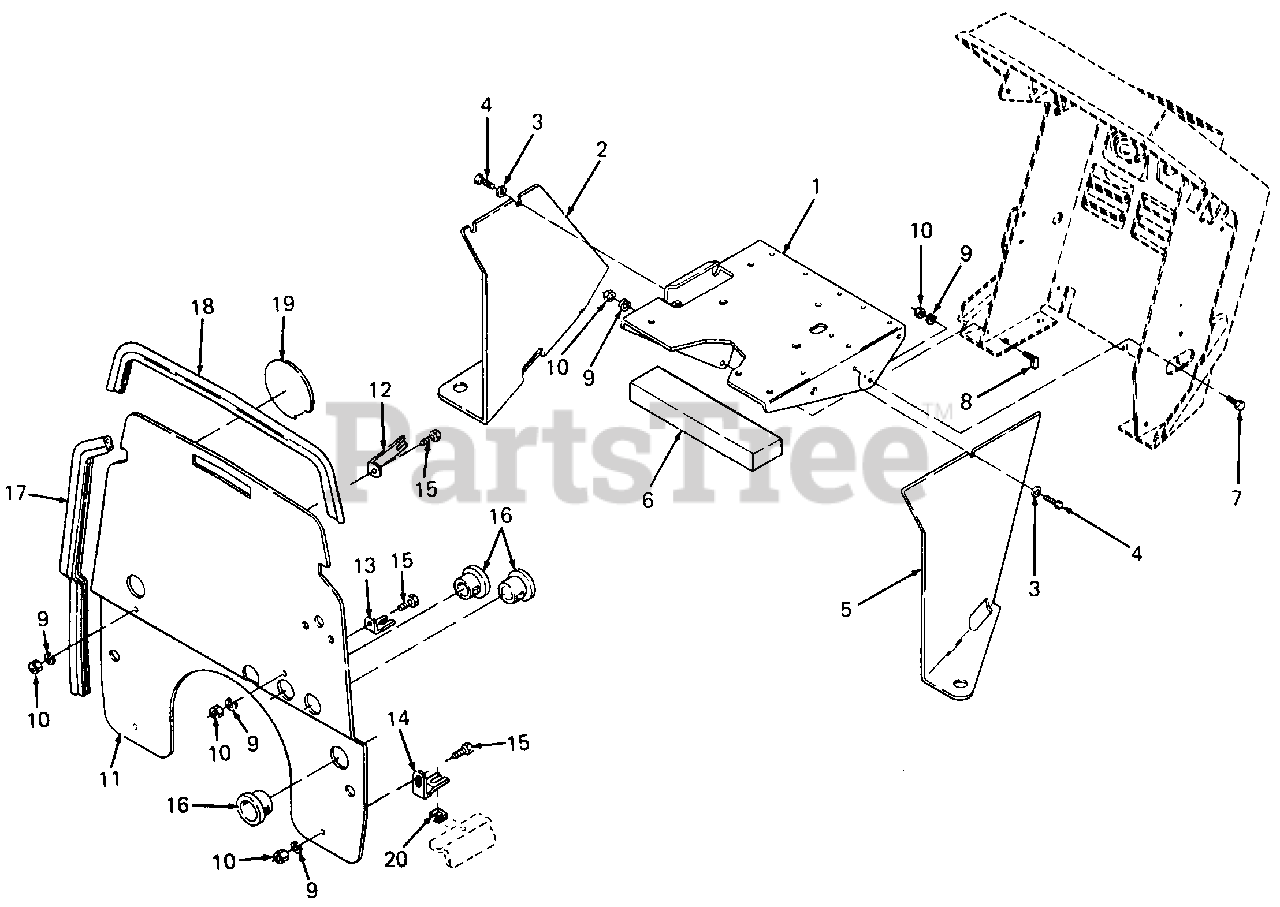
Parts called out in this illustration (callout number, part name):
1	Tray Assy, Battery
2	Baffle, Intake - RH
3	Washer, Bell, .380 X .88 X .060 Thk
4	Screw, Hex Cap, 5/16-18 X 1.0 Lg GR5
5	Baffle, Intake - LH
6	Strip, Foam Gasket Sealing, 10.31 in. Lg
7	Screw, Hex Cap, 1/4-20 X .62 Lg GR5
8	Bolt, J-Type, 1/4-20
9	Washer, Lock, 1/4
10	Nut, Hex, 1/4-20 GR5
11	Baffle, Heat
12	L-Bracket, 1.9 Lg
13	L-Bracket, 1.1 Lg
14	L-Bracket
15	Screw, Hex Cap, 1/4-20 X .5 GR5
16	Bushing, Snap, 7/8 ID
17	Seal, Heat Baffle, 19" Lg
18	Seal, Heat Baffle, 17" Lg
19	Insulator, "+" Battery Post
20	Nut, U-Type, 5/16-18
